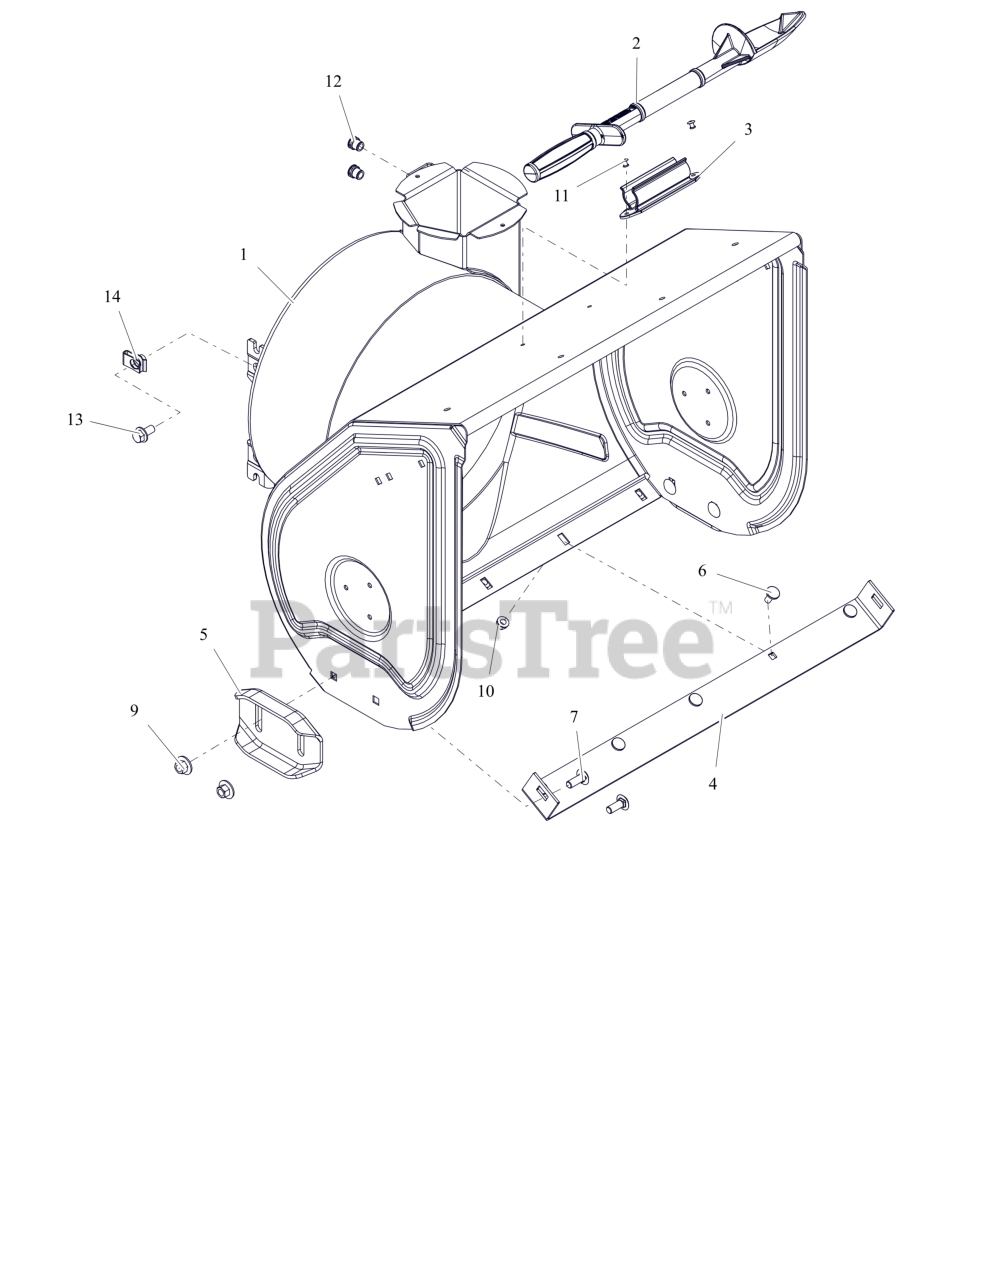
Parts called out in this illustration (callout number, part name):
1	HOUSING, BLOWER W/DECALS 24"
2	DEVICE, SNOW CLEAN OUT
3	MOUNT, SNOW CLEAN OUT
4	BLADE, SCRAPER-24"
5	SKID SHOE, REVERSIBLE - ORANGE
6	BOLT, MODIFIED HEAD CARRIAGE
7	BLT,RHSSN .38-16X1.00 G5 ZCC
9	NUT- CON-LN .375-16 ZC120
10	NUT-LK-TOP-FLG .312-18 GF ZCC
11	RVT, POP .1875 ZCC
12	NUT,THD,INSERT .38-16 ZC120
14	NUT-RTNR .375-16X.37
